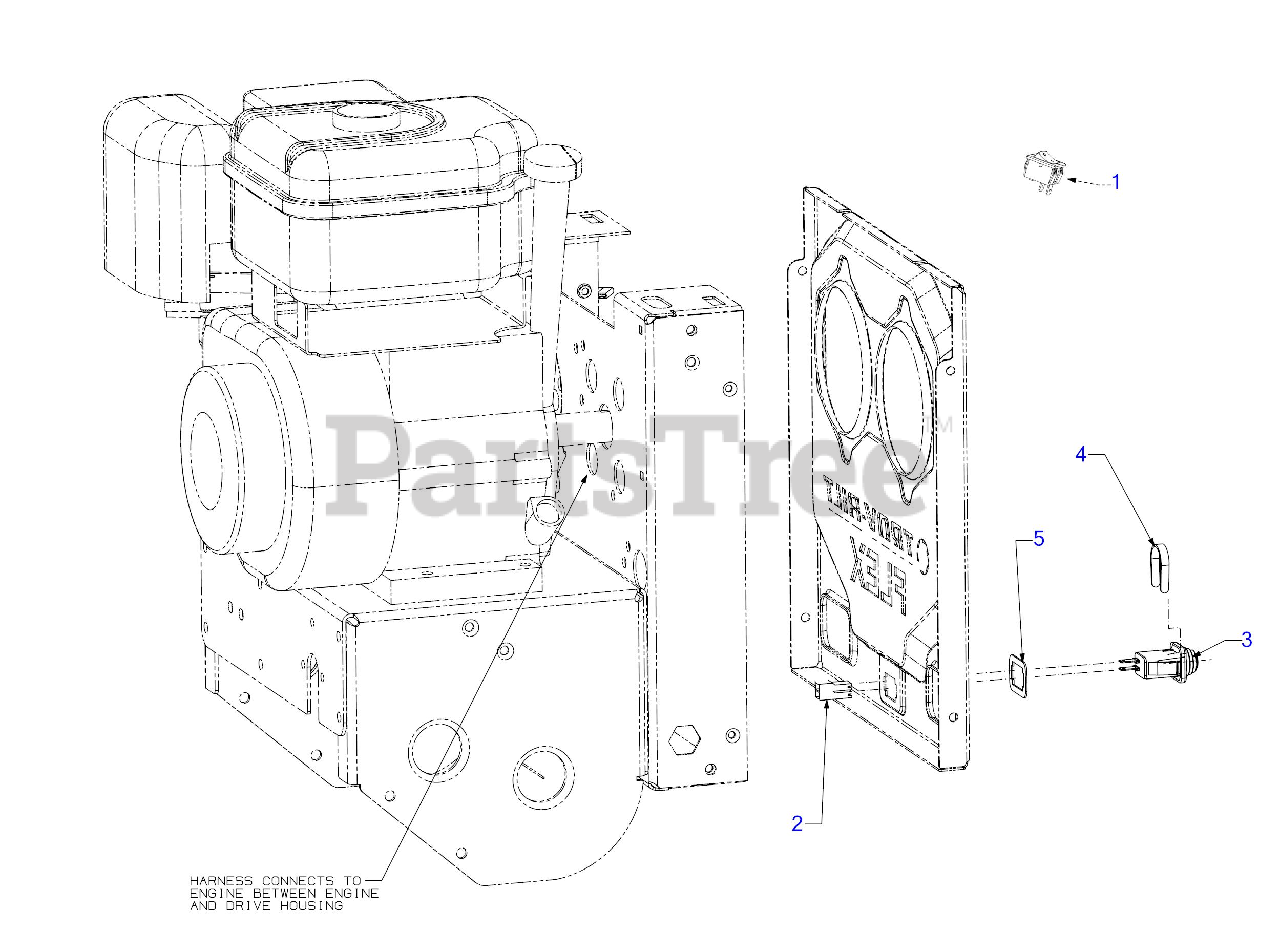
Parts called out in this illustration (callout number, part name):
1	MOMENTARY SWITCH ON/OFF
2	ACCESSORY HARNES
3	PLUNGER SWITCH
4	RETAINING CLIP
5	SPACER PLATE
